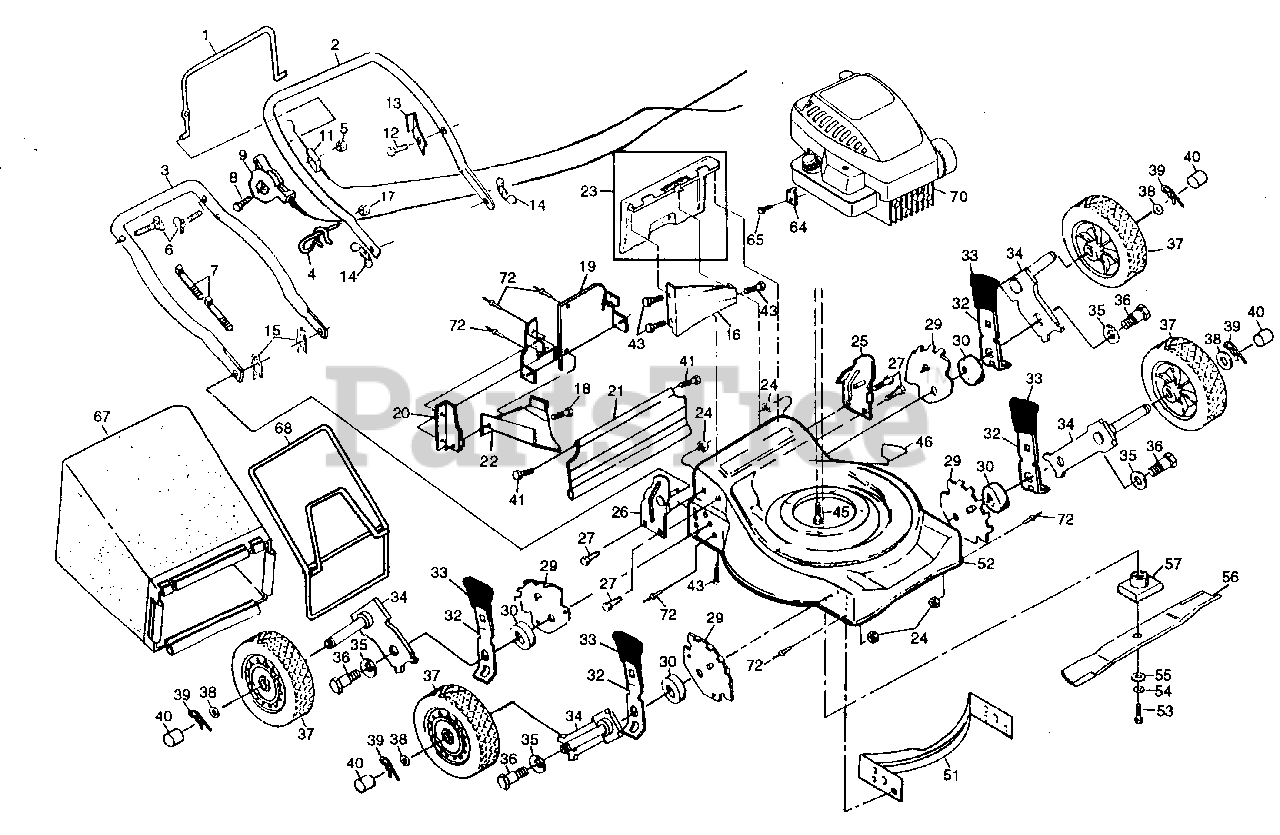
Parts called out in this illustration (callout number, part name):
1	Control Bar (AYP part number)
2	Upper Handle (AYP part number)
3	Lower Handle (AYP part number)
4	Rope Guide
5	Locknut 1/4-20 (AYP part number)
6	Handle Bolt (AYP part number)
7	Wire Tie (AYP part number)
8	Hex Washer Hd Screw 1/4-20 x 2-1/8 (AYP part number)
9	Throttle Control (AYP part number)
11	Engine Zone Control Cable
12	Hex Washer Head Screw #10-24 x 1/2 (AYP part number)
13	Up-Stop Bracket (AYP part number)
14	Wing Nut (AYP part number)
15	Hairpin Cotter (AYP part number)
16	Rear Baffle
17	Keps Locknut 1/4-20 (AYP part number)
18	Self Tapping Screw #10-24 x 1/2 (AYP part number)
19	Back Plate (AYP part number)
20	Side Baffle (AYP part number)
21	Rear Skirt (AYP part number)
22	Discharge Baffle (AYP part number)
23	Rear Door Assembly Kit (AYP part number)
24	Locknut 3/8-16 (AYP part number)
25	Handle Bracket Assembly (Left) (AYP part number)
26	Handle Bracket Assembly (Right) (AYP part number)
27	Screw 5/16-18 x 3/4 (AYP part number)
29	Wheel Adjusting Bracket (AYP part number)
30	Spacer (AYP part number)
32	Selector Spring (AYP part number)
33	Selector Knob (AYP part number)
34	Axle Arm Assembly (AYP part number)
35	Belleville Washer (AYP part number)
36	Shoulder Bolt 3/8-16 (AYP part number)
37	Wheel Assembly (AYP part number)
38	Washer (AYP part number)
39	Retainer Clip (AYP part number)
40	Hubcap (AYP part number)
41	Hinge Screw (AYP part number)
43	Hex Tapping Screw 1/4-20 x 1/2 (AYP part number)
45	Hex Head Thread Rolling Screw 3/8-16 x 1 (AYP part number)
46	Danger Decal (AYP part number)
51	Front Baffle (AYP part number)
52	Housing Assembly (Incl. Ref. #46)
53	Hex Head Screw 3/8-24 x 1-3/8 Grd. 8
54	Helical Lock Washer (AYP part number)
55	Hardened Washer (AYP part number)
56	20" Blade (AYP part number)
57	Blade Adapter (AYP part number)
64	Cable Clamp (AYP part number)
65	Screw #10 x 5/8 (AYP part number)
67	Grass Bag (AYP part number)
68	Catcher Frame
72	Pop Rivet (AYP part number)
